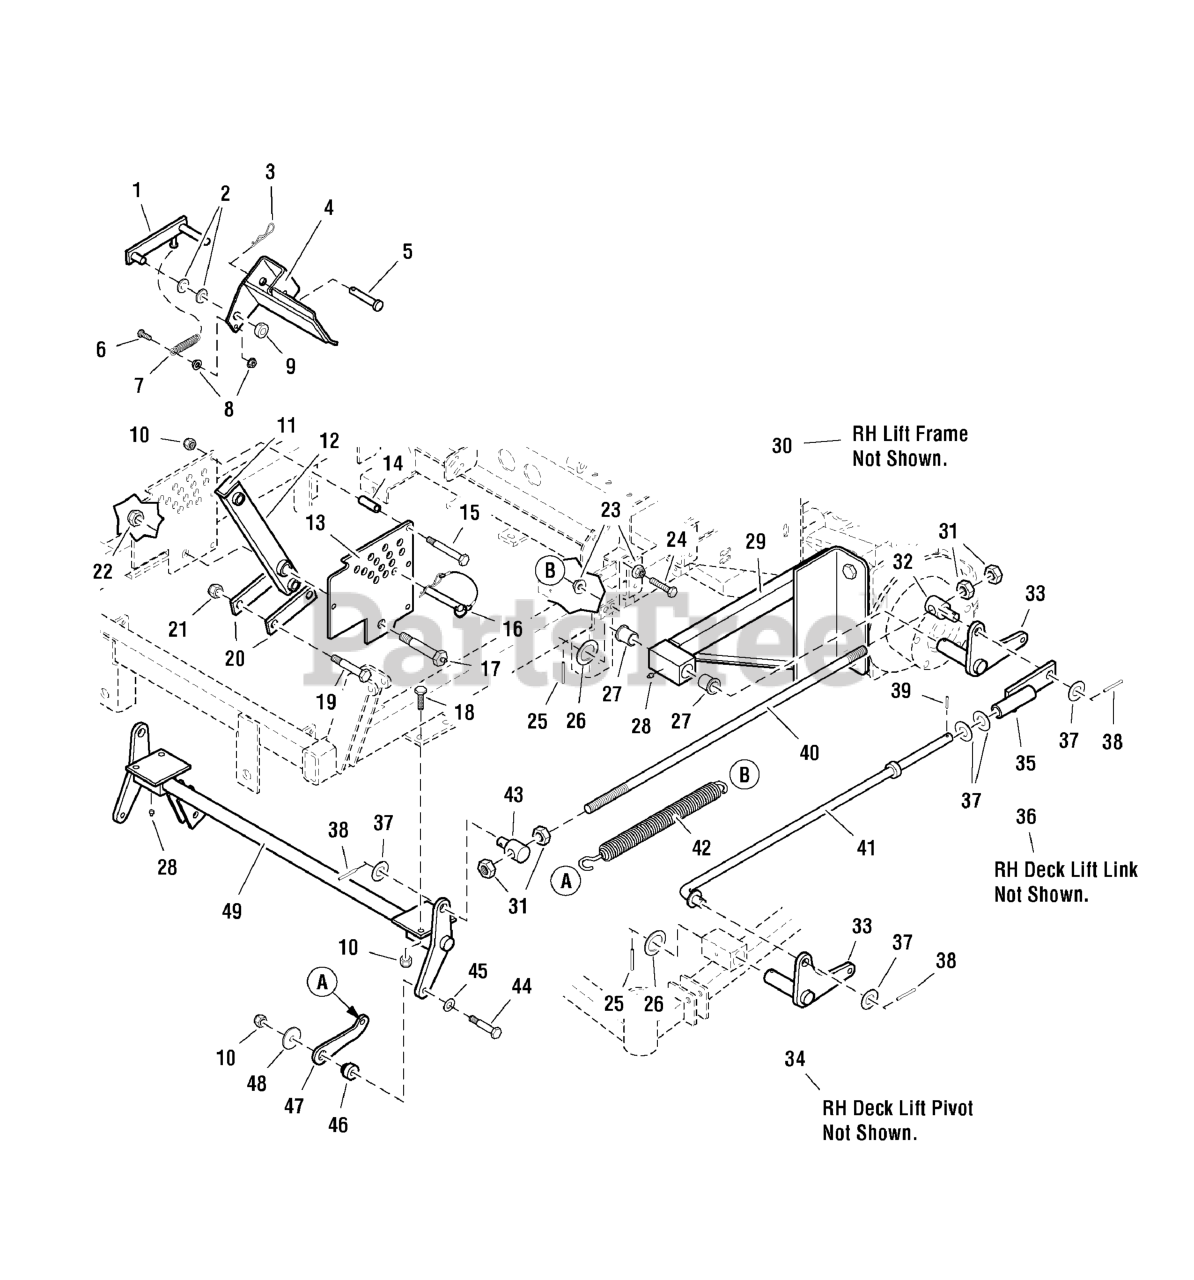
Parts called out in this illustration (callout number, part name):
1	DECK LIFT LOCK
2	WASHER, 1/2 SAE
3	HAIRPIN CLIP
4	WELD, DECK LIFT PEDAL
5	PIN, Clevis, 1/2 x 2-1/2
6	BOLT, 1/4-20 x 3/4
7	SPRING, Extension
8	NUT, 1/4-20 HEX SERR. FLANGE
9	COLLAR, Split, 1/2
10	NUT, 3/8-16 HEX NYLON LOCK
12	ARM, Deck Lift Pivot
13	DECK HEIGHT PLATE
14	SPACER, .38 x .50 x 1.56
15	BOLT, 3/8-16 X 2-3/4" GD5 CZ
16	PIN, 1/2 x 3-1/2 w/ Lanyard
17	LIFT PIVOT BOLT
18	BOLT, 3/8-16 X 1-1/4" GD5 CZ
19	BOLT, 1/2-20 x 3
20	DECK LIFT LINK
21	NUT, Hex, Nylon Lock, 1/2-20
22	NUT, 5/8-11 Hex Jam Nylon Lock
23	NUT, 3/8-16 Hex Serrated Flange
24	BOLT, 3/8-16 x 1-3/4 TFL
25	PIN, Roll, 3/16 x 1-1/2
27	BUSHING, Flange
28	GREASE FITTING
29	ASSM, LIFT FRAME, LH
31	NUT, 5/8-11 Hex
32	SPRING ROD PIVOT
33	DECK LIFT PIVOT - LH
35	DECK LIFT LINK - LH
37	WASHER, 5/8" SAE
38	PIN, Spring, 3/16 x 1-1/4
39	PIN, Roll, 3/16 x 3/4
40	DECK ADJUSTMENT ROD
41	DECK LIFT ROD
42	DECK LIFT SPRING
43	SPRING ROD PIVOT
44	BOLT, 3/8-16 X 2, GD5, CZ
45	WASHER, 3/8 SAE
46	DECK PIVOT BUSHING
47	SPRING LINK
48	WASHER, 3/8 x 2
49	DECK LIFT SHAFT & MOUNT ASSEMBLY
